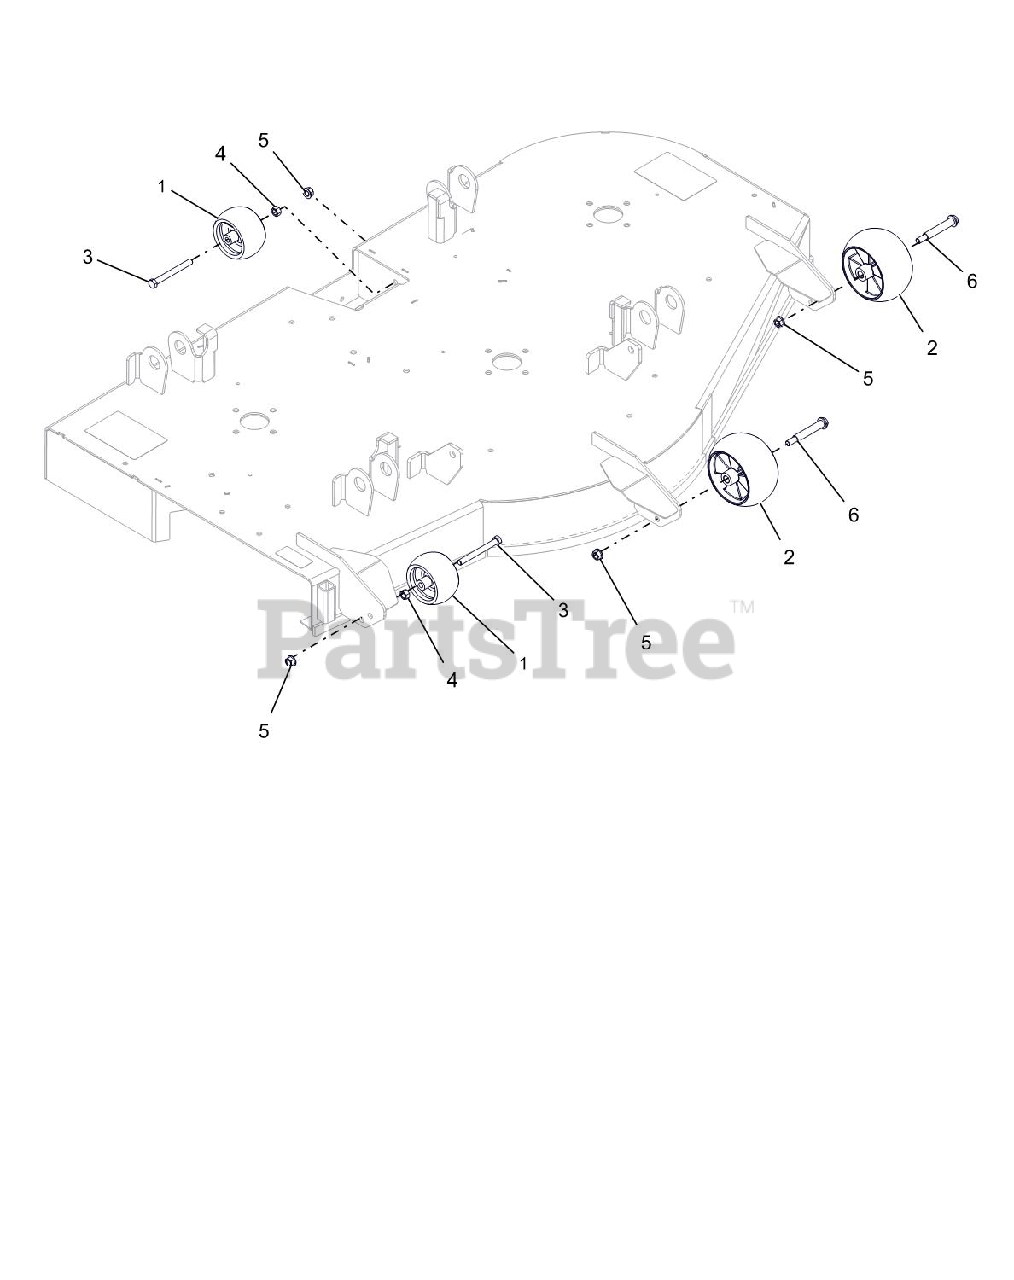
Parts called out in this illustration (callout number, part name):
2	ANTI-SCALP WHEEL - 5X OS
3	@BLT-HEX .38-16X3.50 GR5 YWZC
4	@NUT-HEX .38-16 YWZC
5	@NUT-LK-TOP-FLG .38-16 YWZC
6	BLT-SHLDR .38-16X2.50 HWH G5
